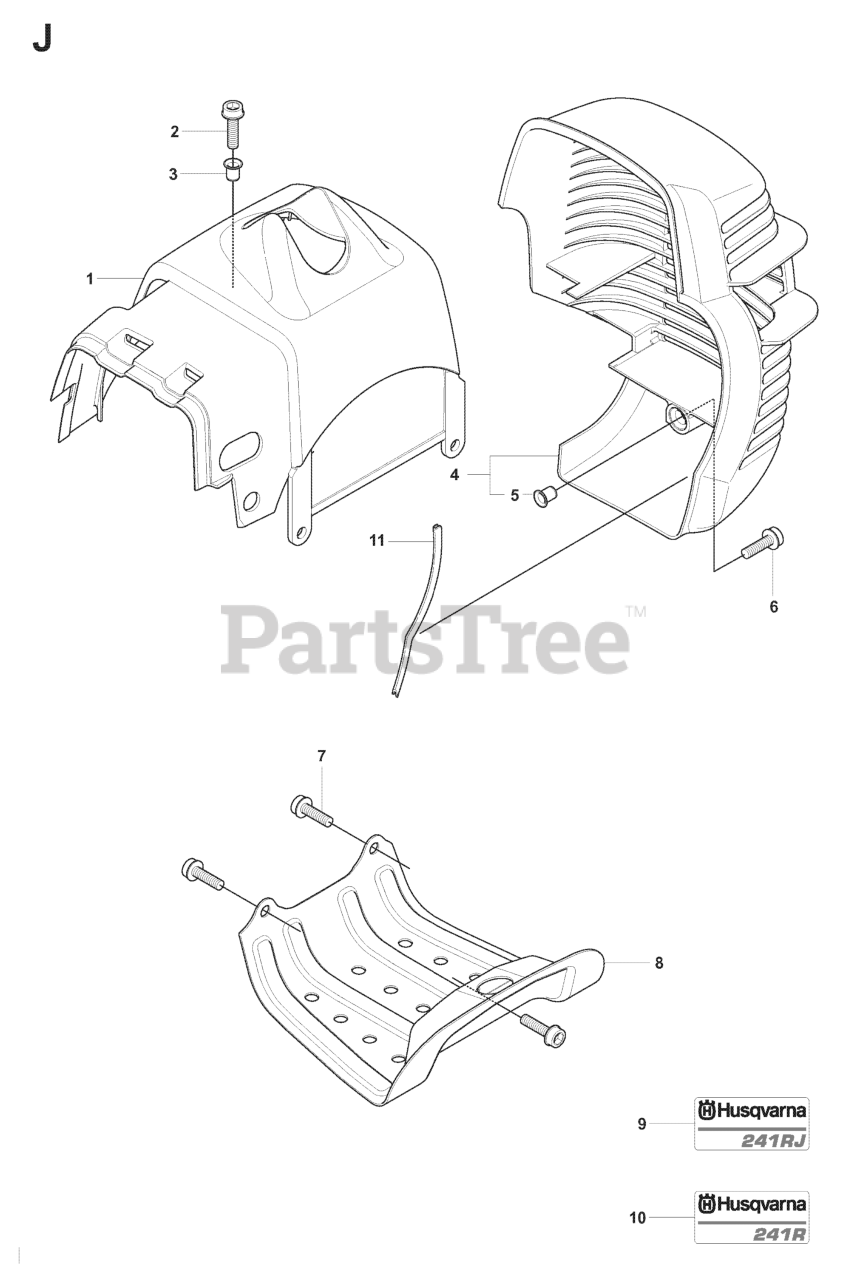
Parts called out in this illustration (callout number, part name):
2	SCREW IHSCFM
4	PROTECTOR
6	SCREW IHSCFM
